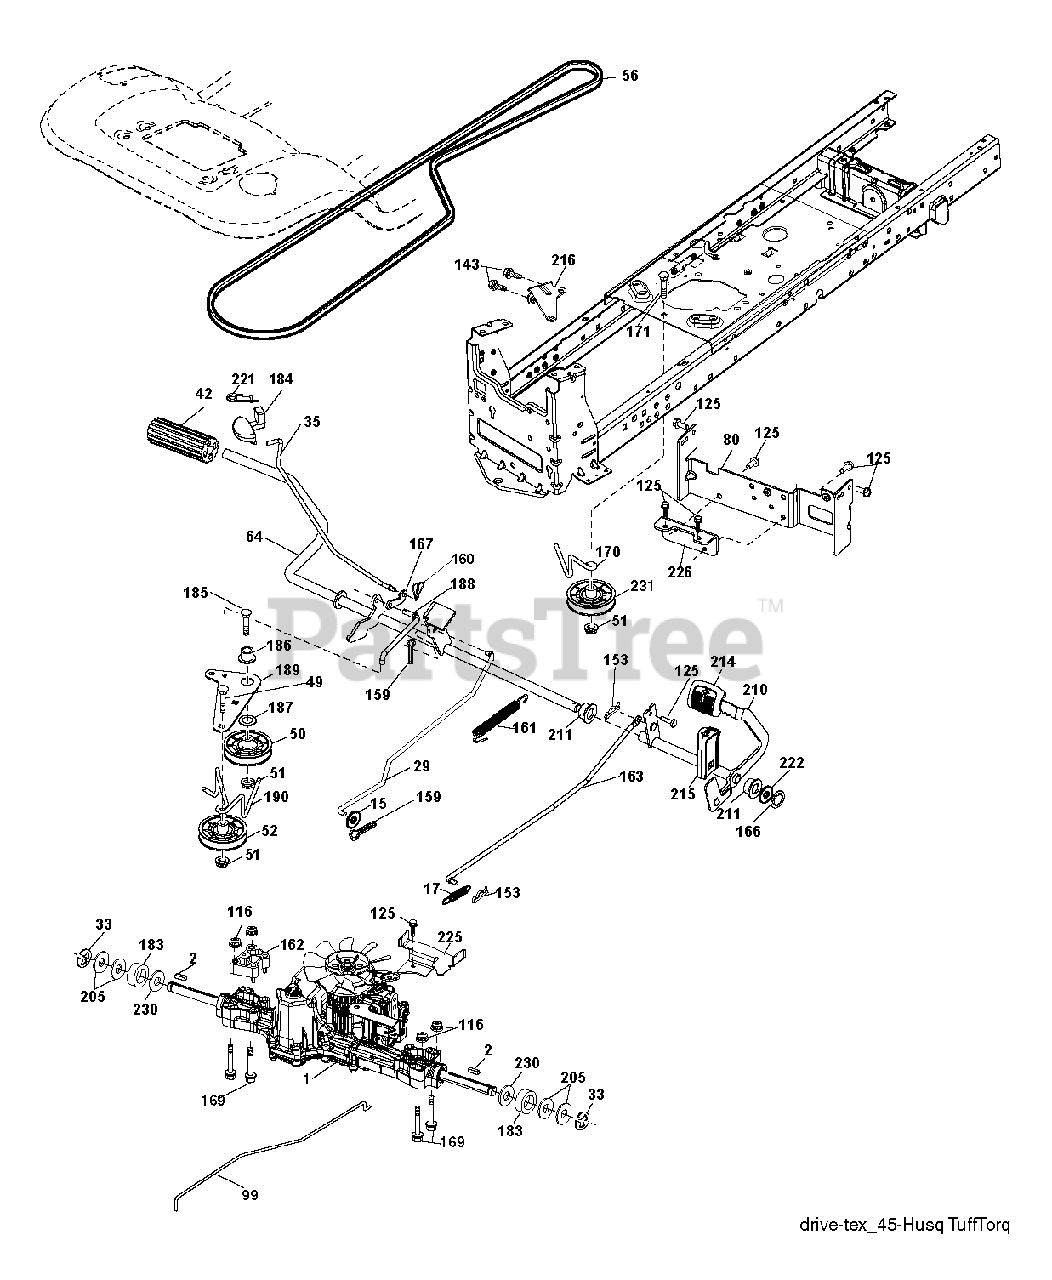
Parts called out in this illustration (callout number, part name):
2	SQUARE KEY
17	SPRING.BRAKE.K46.GREEN
29	ROD.BRAKE.K46
33	E-RING LT
35	ROD.BRAKE.PARKING.LT.T
42	PEDAL COVER T
49	BOLT
50	IDLER.FLAT.910.OFFSET
51	NUT LOCK FLG 3/8-16 UNC
52	IDLER.V-GROOVE.910.OFFSET
64	SHAFT.ASM.PEDAL.BRK.CNTR
80	STRAP TORQUE
99	ROD ASM BYPASS
116	NUT LOCK HEX FLANGE 5/16-18
125	SCREW
153	RETAINER M
159	COTTER PIN
160	RETAINER CLIP
161	SPRING.RETURN.CLUTCH.2006
162	SPACER.TRANSAXLE.18&22
163	ROD.CONTROL.PEDAL.K46
166	NUT.PUSH.625.2006
167	LATCH.BRAKE.SPRING
169	BOLT.HEX.FLNG.5/16-18X3.75
170	KEEPER.V-IDLER.CENTER.
183	SPACER AXLE
184	HANDLE.PAKRING.BRAKE.
186	SPACER.RETAINER
187	WASHER 12/32X2X10GA
188	LINK.CLUTCH.GROUND.DRIVE
189	BELLCRANK.GROUND.DRIVE.TEX.
190	KEEPER.BELLCRANK.DRIVE
210	ROCKER.ASM.PEDAL.CONTR
211	BEARING.NYLON
214	PEDAL.FORWARD.TEX.GT.4
215	PEDAL.REVERSE.TEX.GT.4
216	BRACKET.PULLEY.IDLER.W/TEX
221	RETAINER.SPRING.CLIP.H
222	WASHER 21/32 X 1-1/4 X 10 GA.
225	KEEPER.BELT.TRANSAXLE.K46
226	BRACKET.MOUNT.TORQUE.K46.TLT
230	WASHER.HARDENED
231	IDLER.V-GROOVE.1.688.OFFSET
